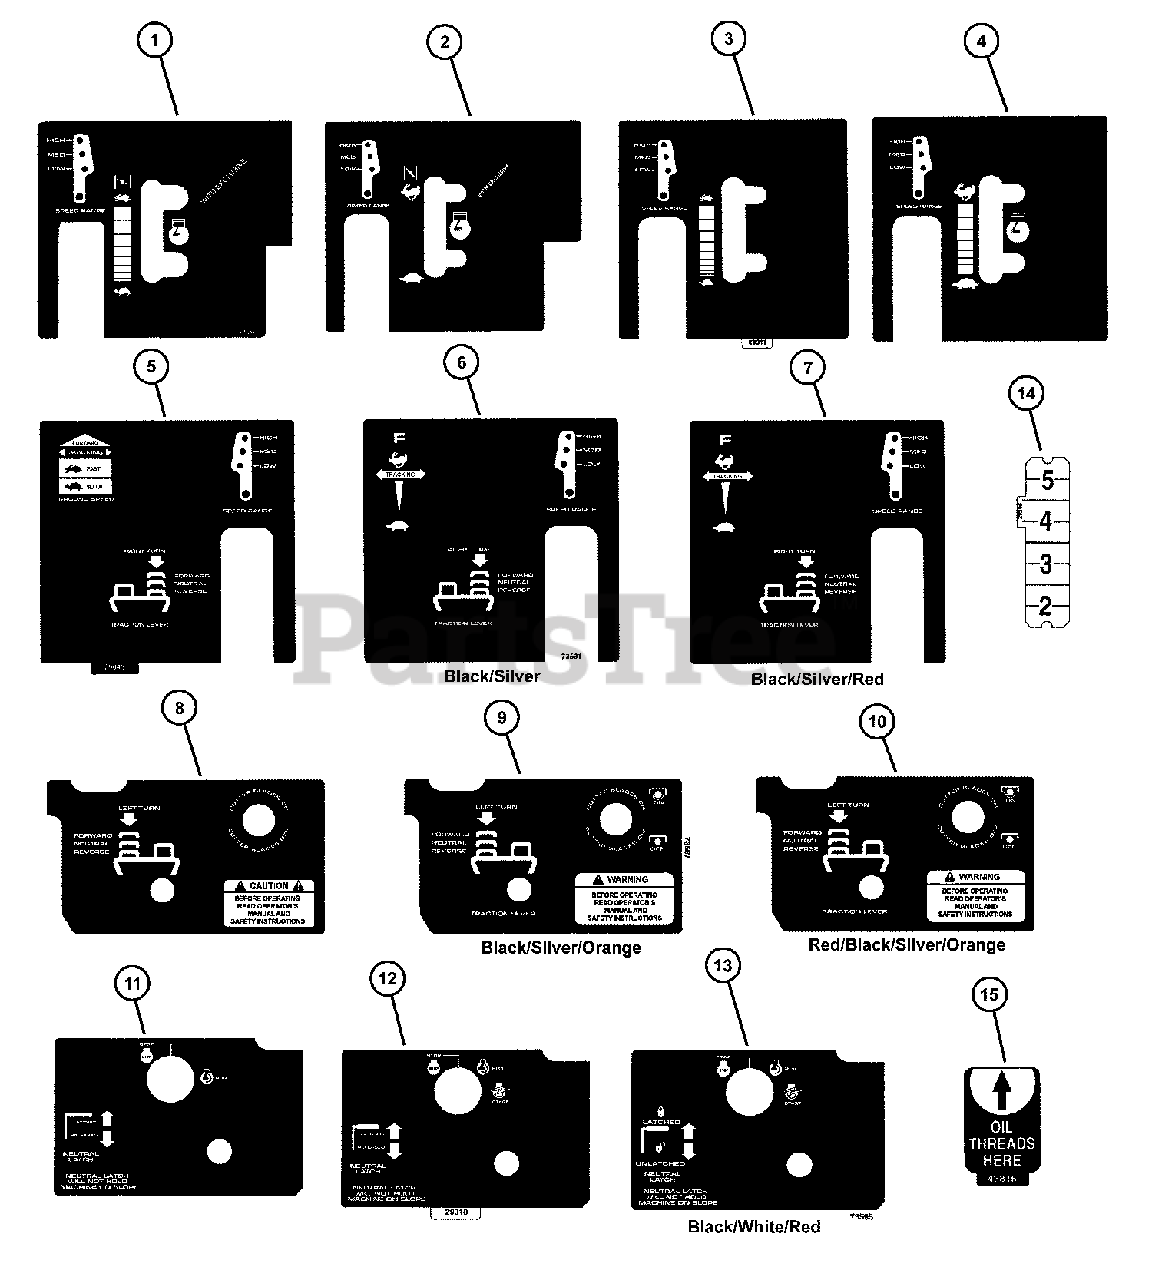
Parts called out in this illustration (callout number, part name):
1	DECAL, Left Panel, Engine Control w/Choke
2	DECAL, Left Panel, Throttle w/Choke (Hydro)
3	DECAL, Left Panel, Engine Control w/o Choke
4	DECAL, Left Panel, Throttle w/o Choke (Hydro)
5	DECAL, Right Panel, Instruction
6	DECAL, Right Panel, Instruction
7	DECAL, Right Panel, Instructions
8	DECAL, Left Panel, Switch
9	DECAL, Left Panel, Switch
10	DECAL, Left Panel, Switch
11	DECAL, Right Panel, Switch
12	DECAL, Right Panel, Switch, Electric Start
13	DECAL, Right Panel, Switch, Electric Start (Hydro)
14	DECAL, Height of Cut
15	DECAL, Oil Threads Here (Adjustable Decks only)
